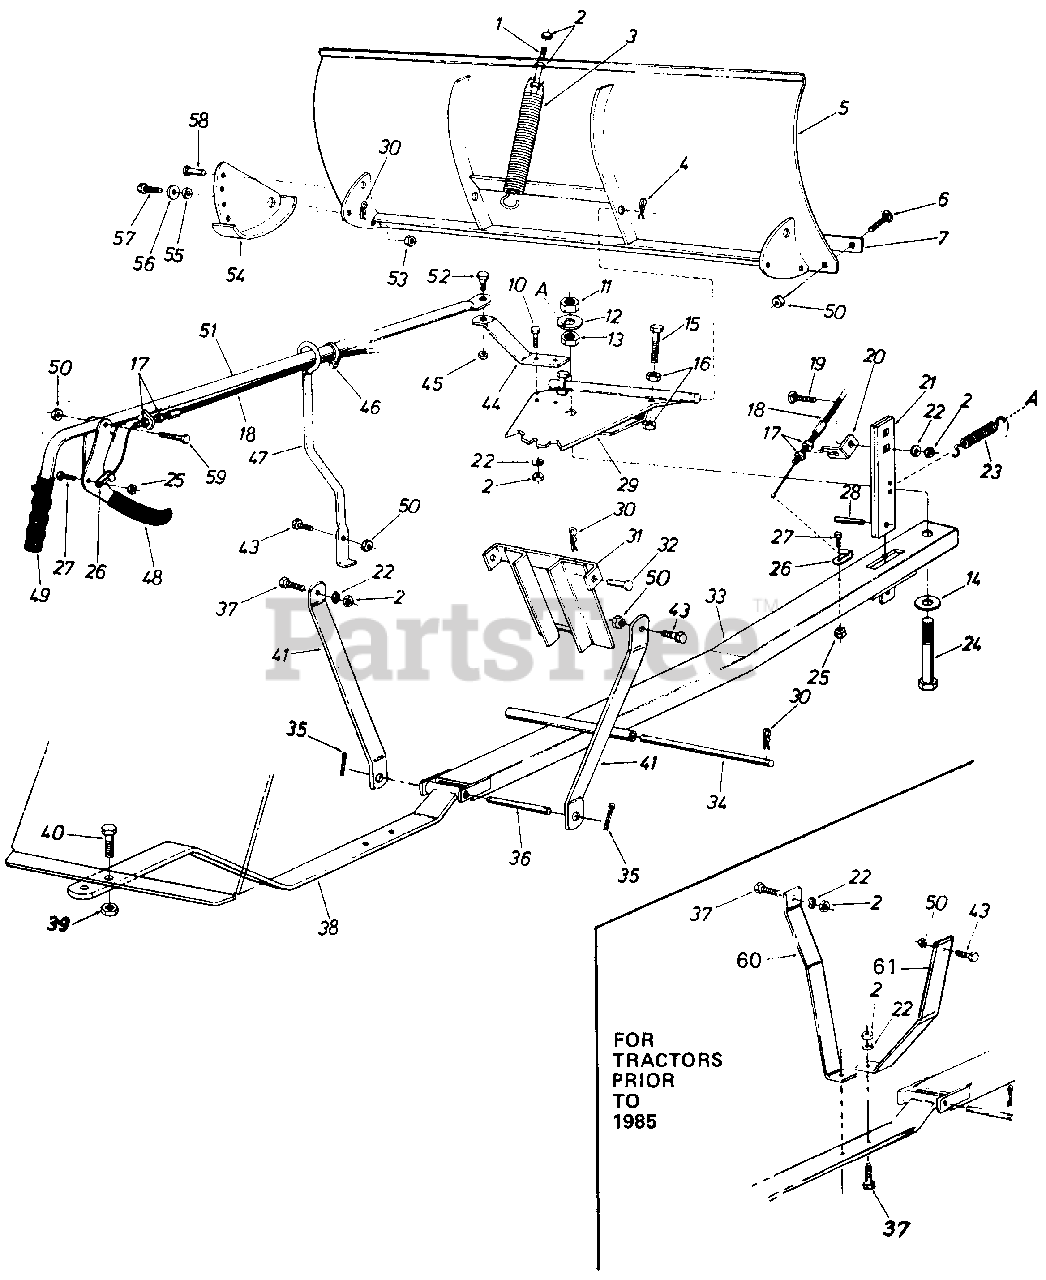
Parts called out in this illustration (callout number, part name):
1	Hex Scr. 3/8-16 x 4.50" Lg.*
2	Hex Nut 3/8-16 Thd.*
3	Blade Adjustment Spring
4	Hair Pin Cotter 5/32" D ia.
5	48" Blade Ass'y.
6	Carriage Bolt 5/ 1 6- 1 8 x.75" Lg.*
7	Wear Plate 48"
10	Hex Scr. 3/8-16 x 1.00" Lg.*
11	Hex L.-Nut 3/4-10 Thd.
12	Fl.-Wash..810" I.D. x 2.00" O.D.
13	Hex Jam Nut 3/4-10 Thd. *
14	Fl.-Wash..810" I.D. x 2.00" O.D.
15	Hex Scr. 1/2-13 x 2.00" Lg.*
16	Hex Nut 1/2-13 Thd. *
17	Hex Jam Nut 5/16- 24 Thd.*
18	Control Cable Ass'y.
19	Carriage Bolt 3/8-16 x 1.25" Lg.*
20	Cable Guide Bracket
21	Angle- Lock Bar
22	L.-Wash. 3/8" Scr.*
23	Angle Lock Spring
24	Hex Scr. 3/4-10 x 4.00" Lg.
25	Hex L.-Nut 1/4-20 Thd.
26	Clevis Lanyard F itt i ng
27	Hex Scr. 1/4-20 x .75" Lg.*
28	Spring Pin Spirol 1/4" Dia. x 1.00" Lg.
29	Pivot Plate Ass'y.
30	HairPin Cotter3/32" Dia.
31	Guide Bracket Ass y.
32	Clevis Pin 1/2" Dia. x 1.00" Lg.
33	Push Bar Ass y.
34	Lift Shaft
35	Cotter P i n 5/32" D ia. x 1.00" Lg.*
36	Pivot Pin
37	Hex Scr. 3/8-16 x 1.25" Lg.*
38	Hanger Bracket Ass'y.
39	Hex L.-Nut 5/8-11 Thd
40	Hex Sc;. 5/8-11 x 1.50" Lg.*
41	Hanger Link
43	Hex 5/16-18 x 1.00" Lg. *
44	Blade Pivot Bracket
45	Hex Jam Nut 3/8-16 Thd.
46	Nylon Cable Tie
47	Tube Guide Ass'y.
48	Clutch Grip Ass'y.
49	Grip- 3/4" Handle
50	Hex L-Nut 5/16-18 Thd.
51	Tube Handle Ass'y.
52	Shld. Scr. - Special 3/8-16 Thd.
53	Hex L.-Nut 3/8-16 Thd.
54	Skid Assembly
55	Spacer
56	Fl.-Wash..385" I.D. x 1.00" O.D.
57	Hex Scr. 3/8-16 x .75" Lg.*
58	Clevis Pin 5/16" Dia. x.75" Lg.
59	Hex Scr. 5/16-18 x 1.50" Lg.
60	Mounting Brkt.-L.H.
61	Mounting Brkt.-R.H.
